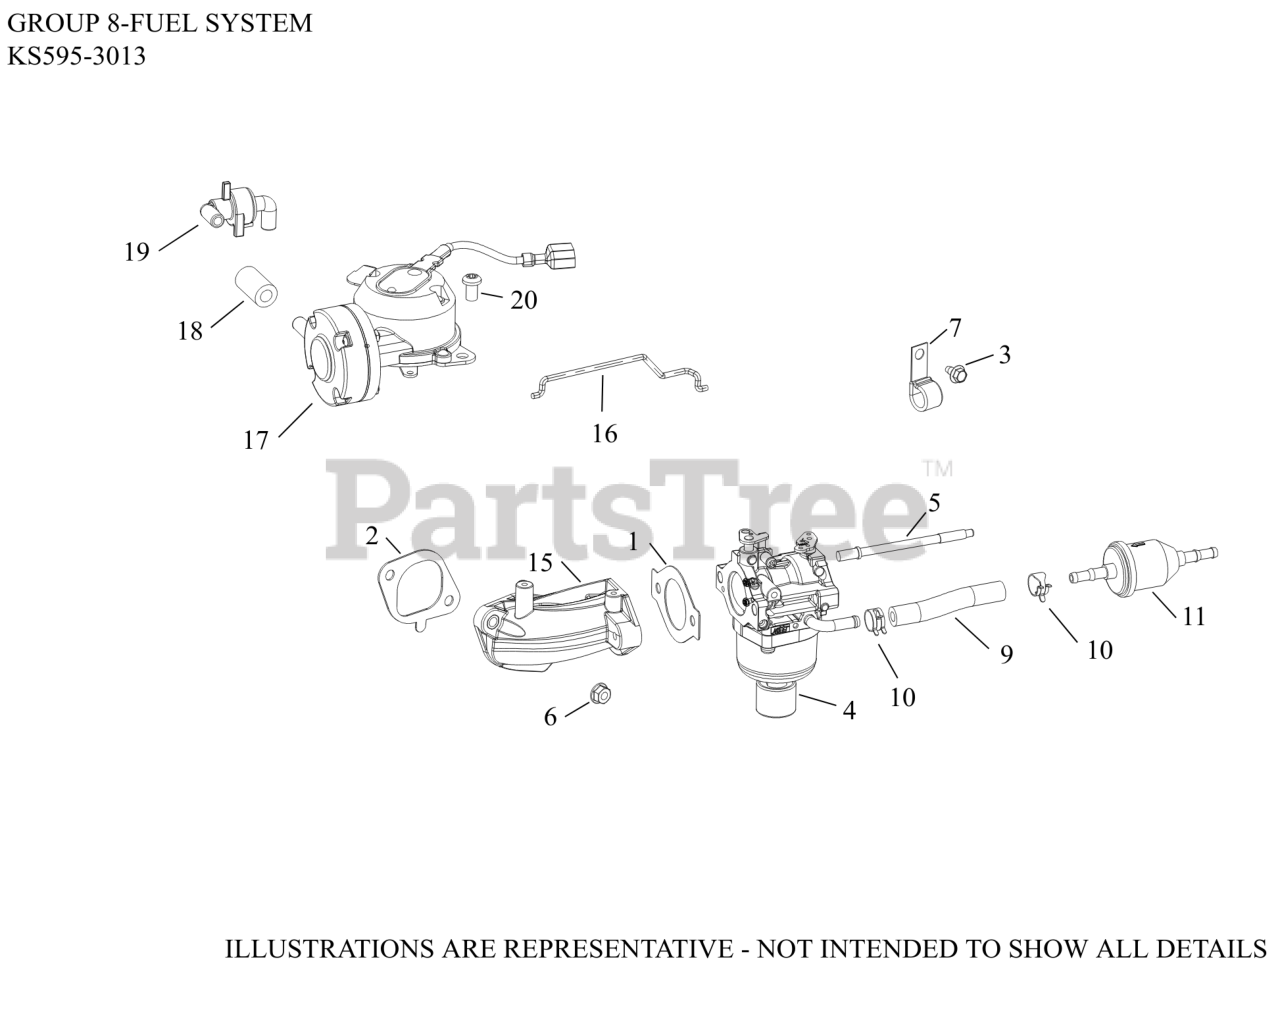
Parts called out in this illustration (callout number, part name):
1	GASKET, CARBURETOR (THROTTLE)
2	GASKET, INTAKE MANIFOLD
3	SCREW, THREAD FORMING
4	KIT,CARB(NIKKI)
5	STUD, CARBURETOR
6	NUT, FLG M6X1.0
7	CLIP, CABLE
9	HOSE,LW PERM.FUEL 24.00"-USE 25 111 81-S
10	SPRING CLAMP, HOSE
11	FILTER,FUEL 75 MICRON (GRAVTY FEED)
15	MANIFOLD, INTAKE ASSY
16	LINKAGE, CHOKE
17	DIAPHRAGM ASSY
18	HOSE, VACUUM
19	CHECK VALVE ASSY
20	SCREW, K40 X 1.79 TFS
NI	HIGH ALTITUDE KIT (5000 FT)
NI	KIT, OVERHAUL
NI	KIT, CHOKE SHAFT
NI	KIT, O-RING
NI	KIT, SOLENOID (NIKKI)
NI	KIT, BOWL WITH O-RINGS
NI	KIT, FLOAT AND INLET NEEDLE FOR GRAVITY
NI	KIT, THROTTLE SHAFT
